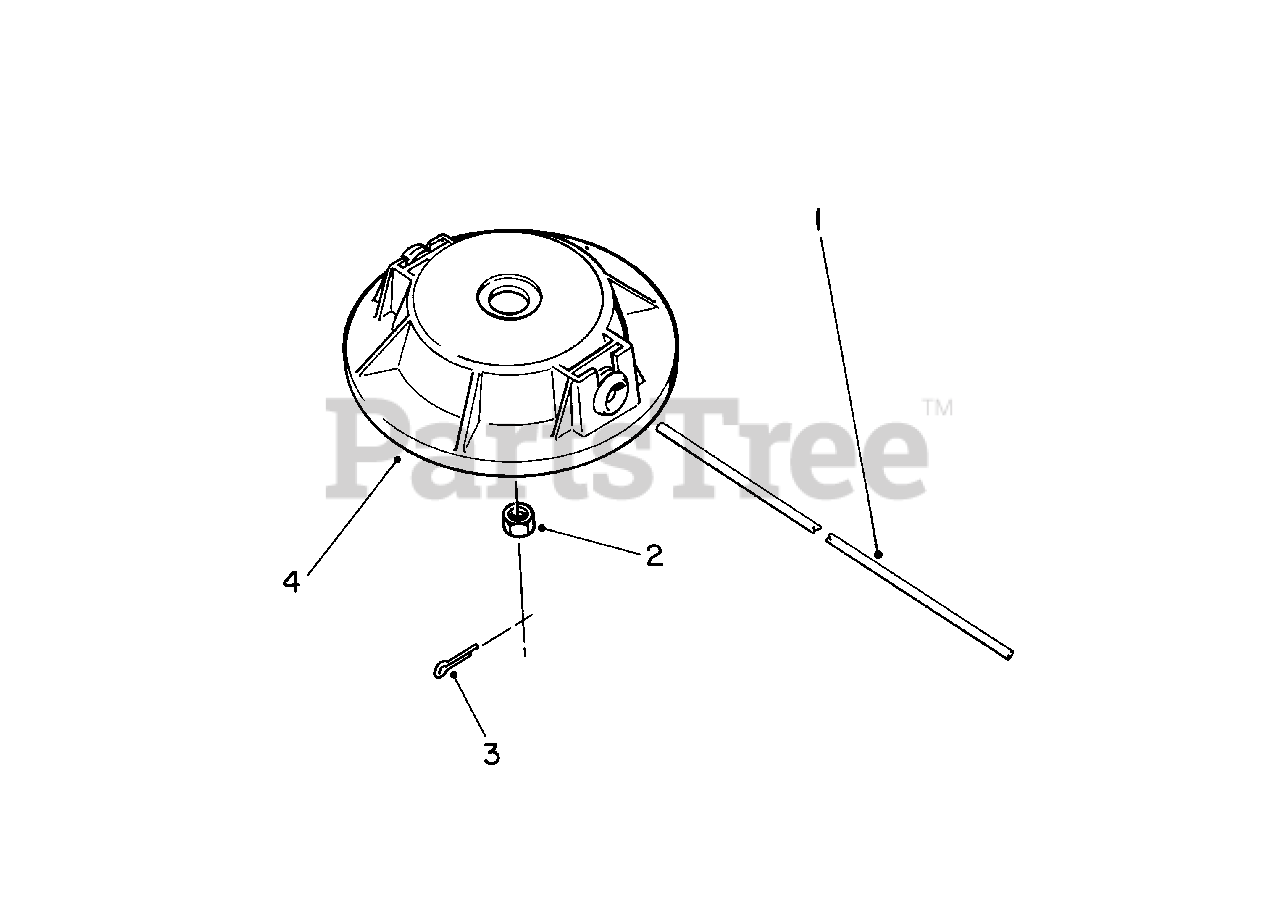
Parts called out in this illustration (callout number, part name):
1	Line-Cutting
2	Nut Hex.
3	Pin-Cotter
4	Cutter Head Assembly
